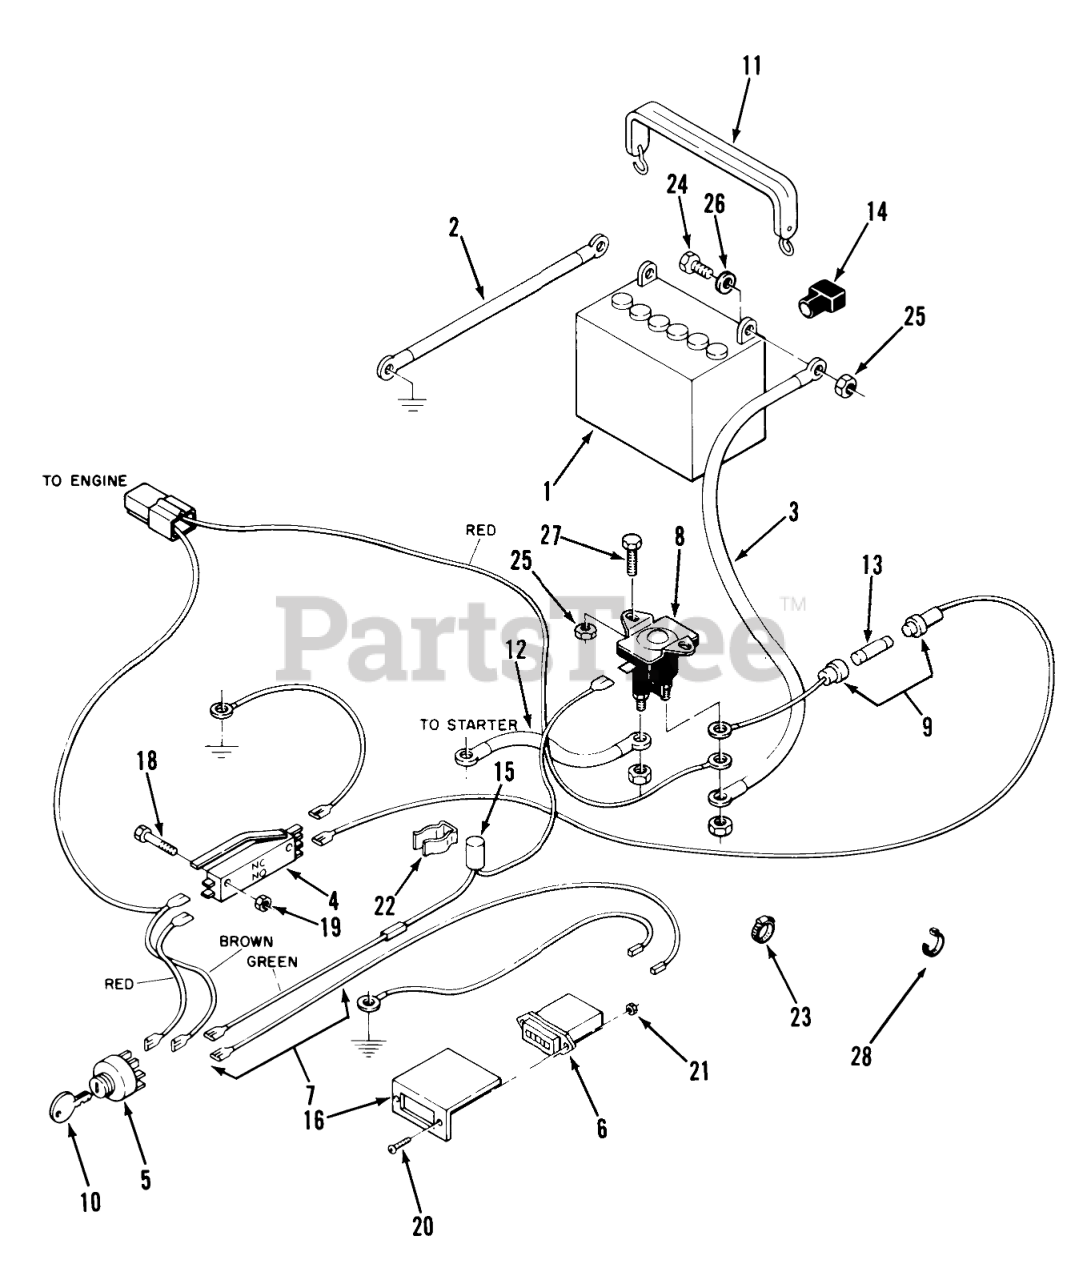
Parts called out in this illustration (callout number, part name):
1	Battery
2	Battery to Ground Cable
3	Solenoid to Starter Cable
4	SAFETY SWITCH
5	SWITCH ASSY
6	Hourmeter
7	Wiring Harness (less items 2, 3, 12 & Hourmeter Ground Wire)
8	SOLENOID-STARTER
9	20 amp. Fuse Holder Assembly
10	Key-EL
11	Battery Hold Down
12	ASSY-WIRE 20226-Z87
14	Boot
15	Mercury Parking Brake Switch
16	Hourmeter Bracket
18	BOLT SCREW 10-32X1
19	Nut
21	Hex Nut
22	CLIP MERC SW C-100
23	CLAMP
24	Bolt
25	Nut 1/4-20
26	WASHER
27	Bolt
28	PLASTIC TIE
